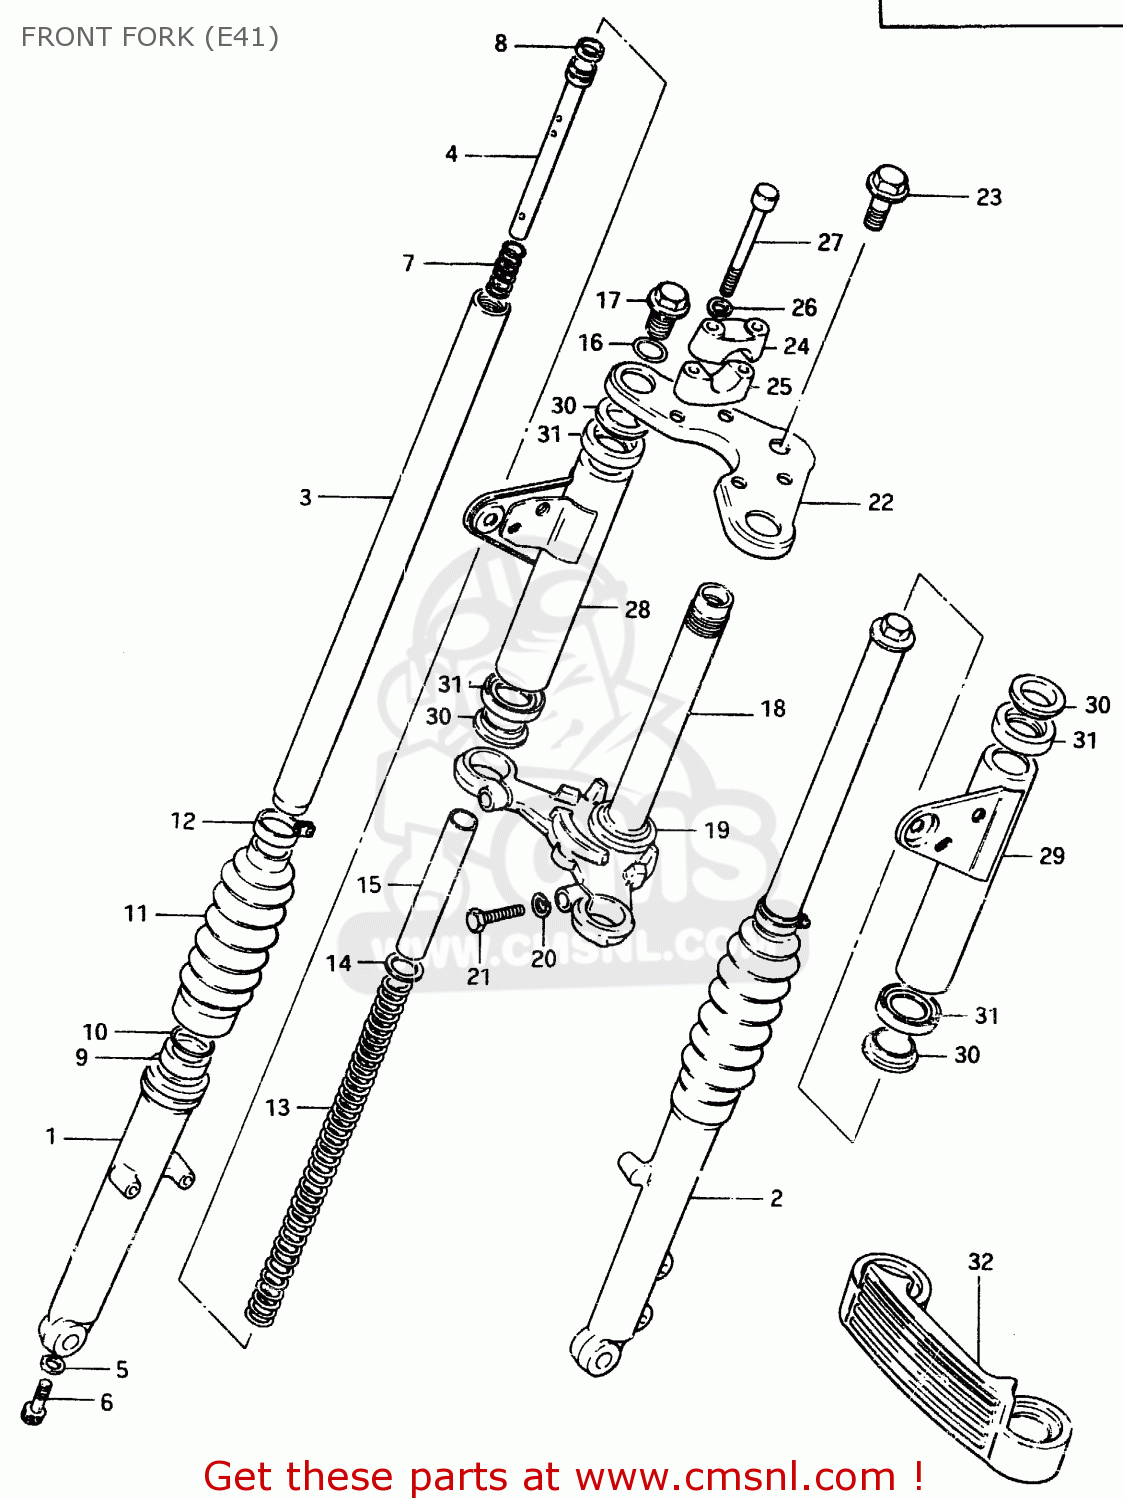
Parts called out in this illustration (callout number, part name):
1	OUTER TUBE, RH
2	OUTER TUBE, LH
3	INNER TUBE
4	CYLINDER
5	GASKET (NAS)
6	BOLT(8X27)
7	SPRING,REBOUND
8	RING,PISTON
9	SEAL,OIL
10	RING,OIL SEAL STOPPER
11	BOOT
12	BAND
13	SPRING
14	JOINT,SPRING
15	SPACER,SPRING
16	O-RING,FORK INNER TUBE
17	CAP
18	STEERING STEM
19	RACE,STEERING OUTER LWR
20	LOCK WASHER
21	BOLT 10X30
22	STEM HEAD, STEERING
23	BOLT
24	HOLDER,HANDLEBAR
25	HOLDER,HANDLE UPR
26	LOCK WASHER
27	WASHER
28	BRACKET, HEADLAMP RH
29	BRACKET, HEADLAMP LH
30	CUSHION
31	GUIDE, COVER
32	COVER
